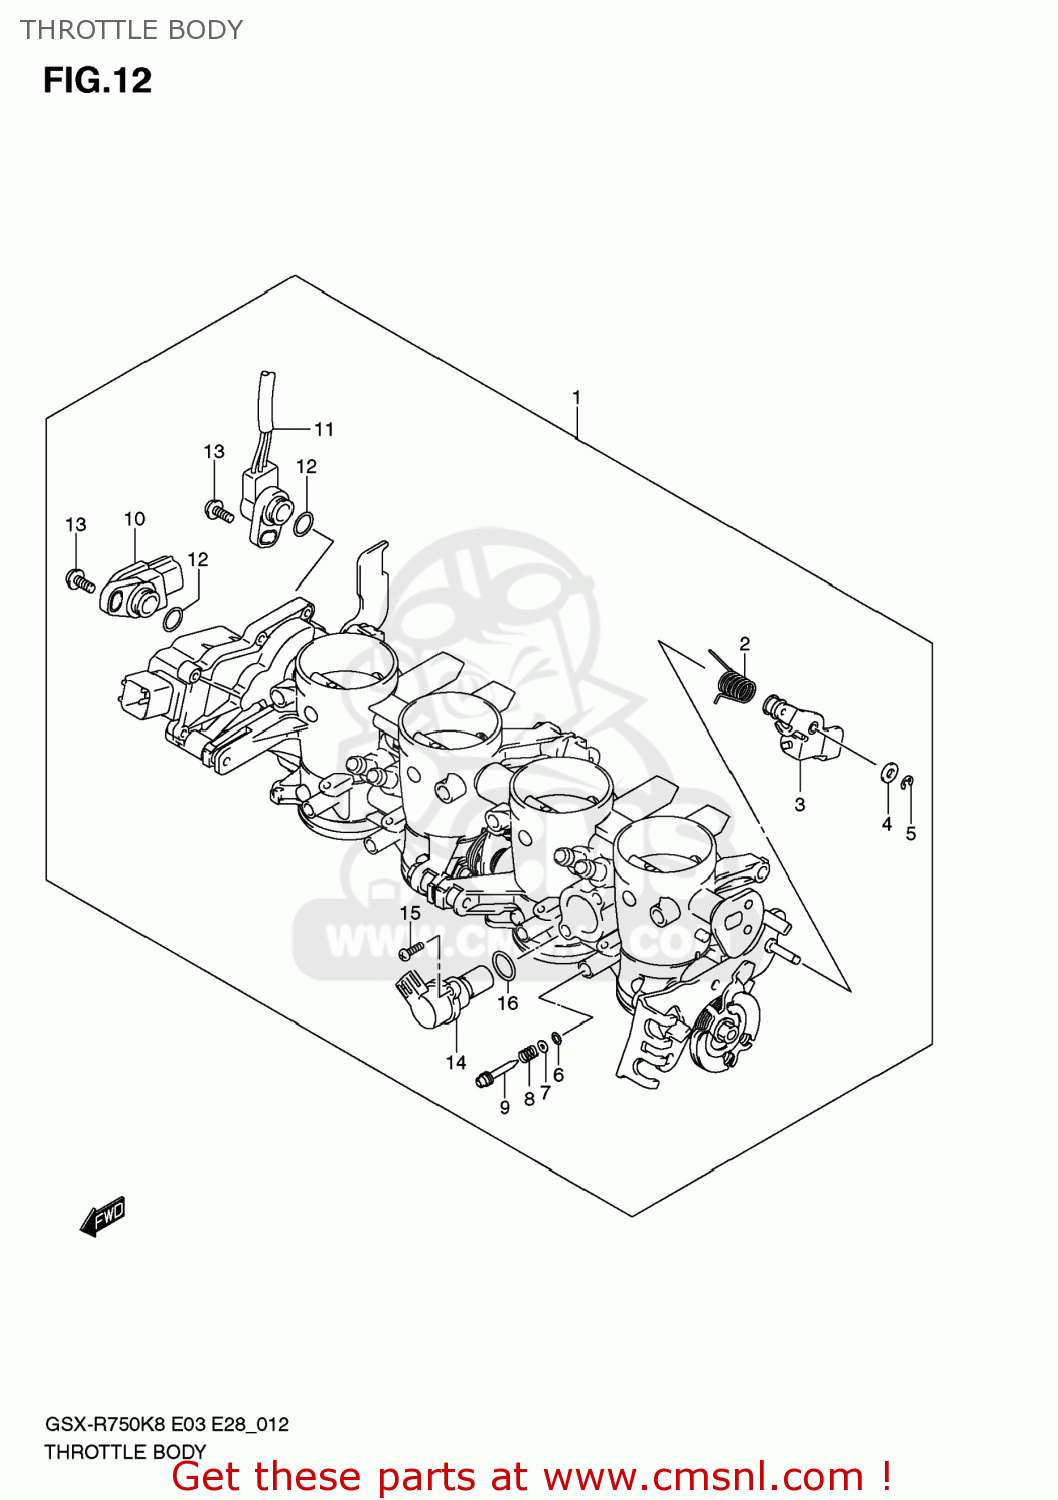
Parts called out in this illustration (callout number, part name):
1	BODY ASSY,THROTTLE
2	SPRING,TORSION
3	LEVER ASSY,LINK
4	PACKING (NAS)
5	E RING
6	O RING,PILOT AIR SCREW
7	WASHER
8	SPRING,THROTTLE SCREW
9	SCREW
10	SENSOR ASSY
11	SENSOR ASSY,TH
12	O RING
13	SCREW
14	VALVE,ISC
15	SCREW
16	O RING
